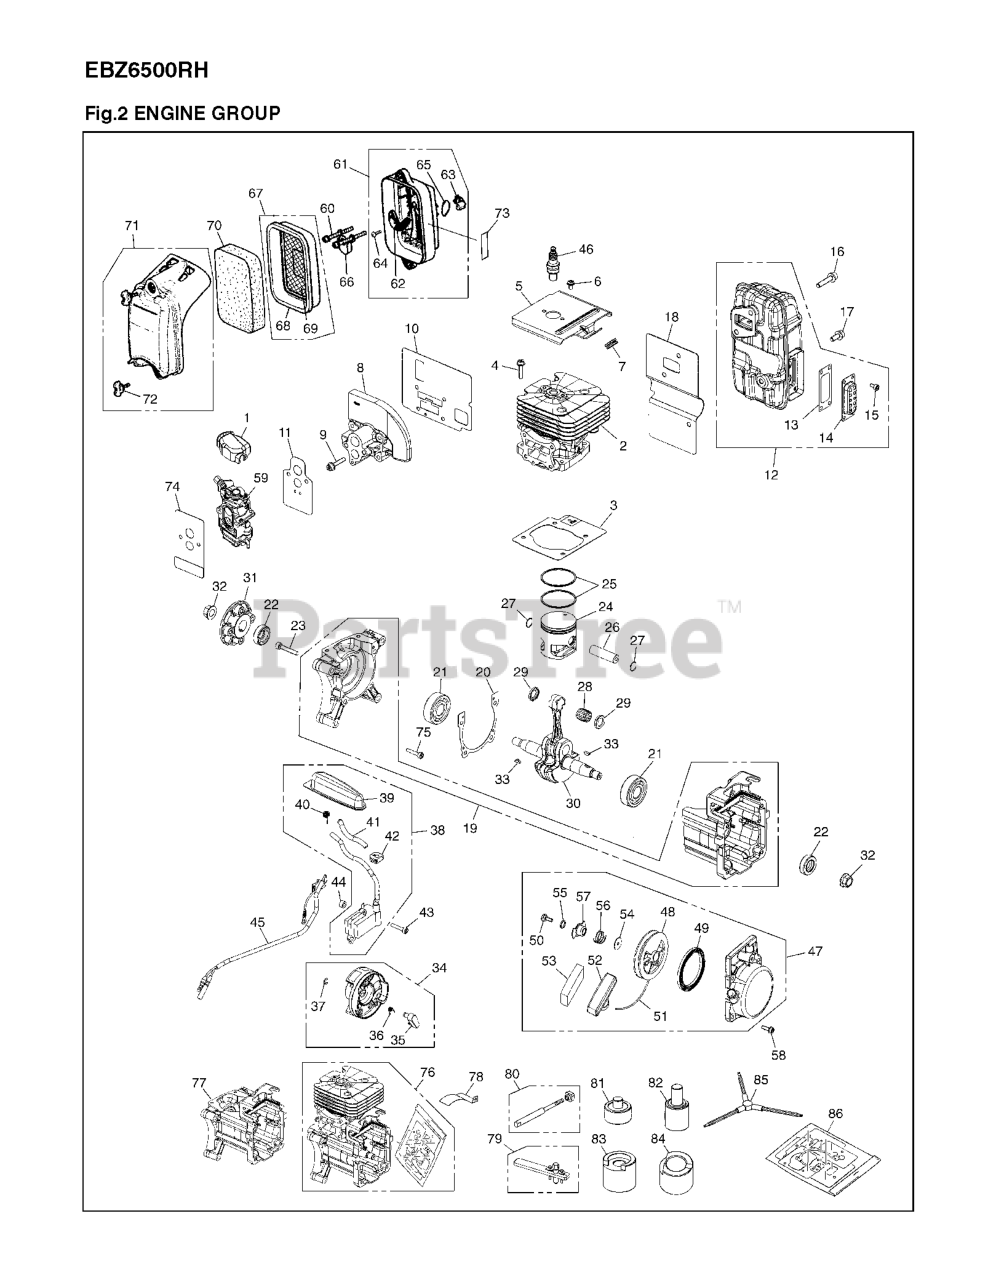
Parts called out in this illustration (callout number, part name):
2	CYLINDER ASSY
4	BOLT
8	INSULATOR
12	MUFFLER ASSY
13	SPARK ARRESTER
14	DIFFUSOR
19	CRANKCASE COMP.
21	BALL BEARING
22	SEAL
27	SNAP RING
28	BEARING
30	CRANKSHAFT COMP.
31	COUPLING
33	KEY
34	ROTOR ASSY
38	COIL COMPLETE
40	SPRING PLUG
42	GROMMET
43	BOLT TORX
44	SPACER
46	PLUG CMR7H
47	RECOIL ASSY
52	KNOB
53	COVER
54	WASHER
56	SPRING FRICTION
57	PLATE
59	CARBURETOR
61	AIR FILTER HOLDER ASSY
62	PLATE
64	SCREW
67	GASKET
69	SCREEN
70	AIR FILTER
71	COVER ASSY.
73	LABEL,CHOKE
76	SHORT BLOCK
77	CRANKCASE ASSY
79	PULLER ASSY
80	ROD ASSY
81	BEARING GUIDE
82	OILSEAL GUIDE
83	SUPPORT CRANKCASE - F
84	SUPPORT CRANKCASE -S
85	WRENCH (RPLS 267096410)
86	GASKET KIT
